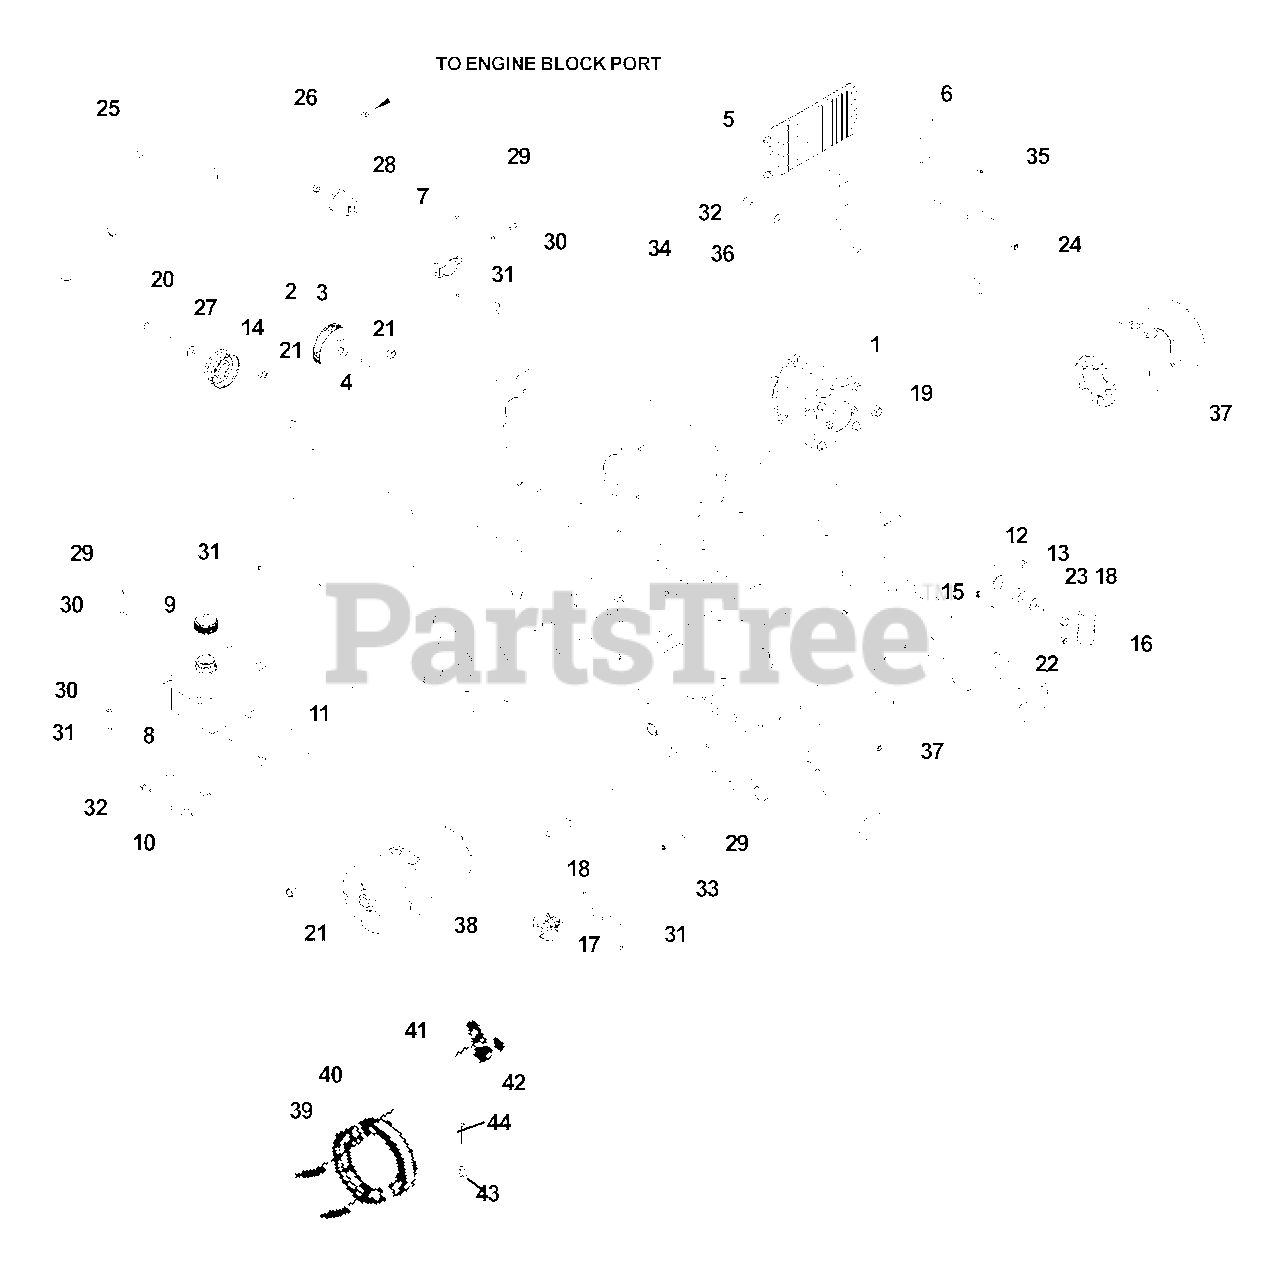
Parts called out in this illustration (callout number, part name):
2	Sheave, pump
3	Setscrew, 5/16-18 x 3/4
4	Key, metric
6	Mount, cooler
7	Clamp, oil sender
10	Tank mount, right
11	Tank, mount, left
14	Pulley, idler
17	Mount, filter
18	Bolt, 1/2-13 x 2 1/2
19	Bolt, 1/2-13 x 1 1/4, serrated head
20	Bolt, 3/8-16 x 3
21	Nut, 1/2-13, nyloc
22	Nut, 3/8-16, nyloc
23	Washer, 1/2
24	Nut, 5/16-18, nyloc
25	Belt, pump
27	Washer, 3/8, SAE
28	Sender, oil pressure
29	Bolt, 1/4-20 x 3/4
30	Washer, 1/4
31	Nut, 1/4-20, nyloc
32	Bolt, 5/16-18 x 1
33	Lockwasher, 1/4
34	Bolt, 1/4-20 x 1
35	Screw, #10 x 5/8, tapping
36	Washer, 5/16
37	Wheel motor, left
38	Wheel motor, right
39	Return spring
40	Shoe assembly
43	Castle nut
44	Cotter pin
